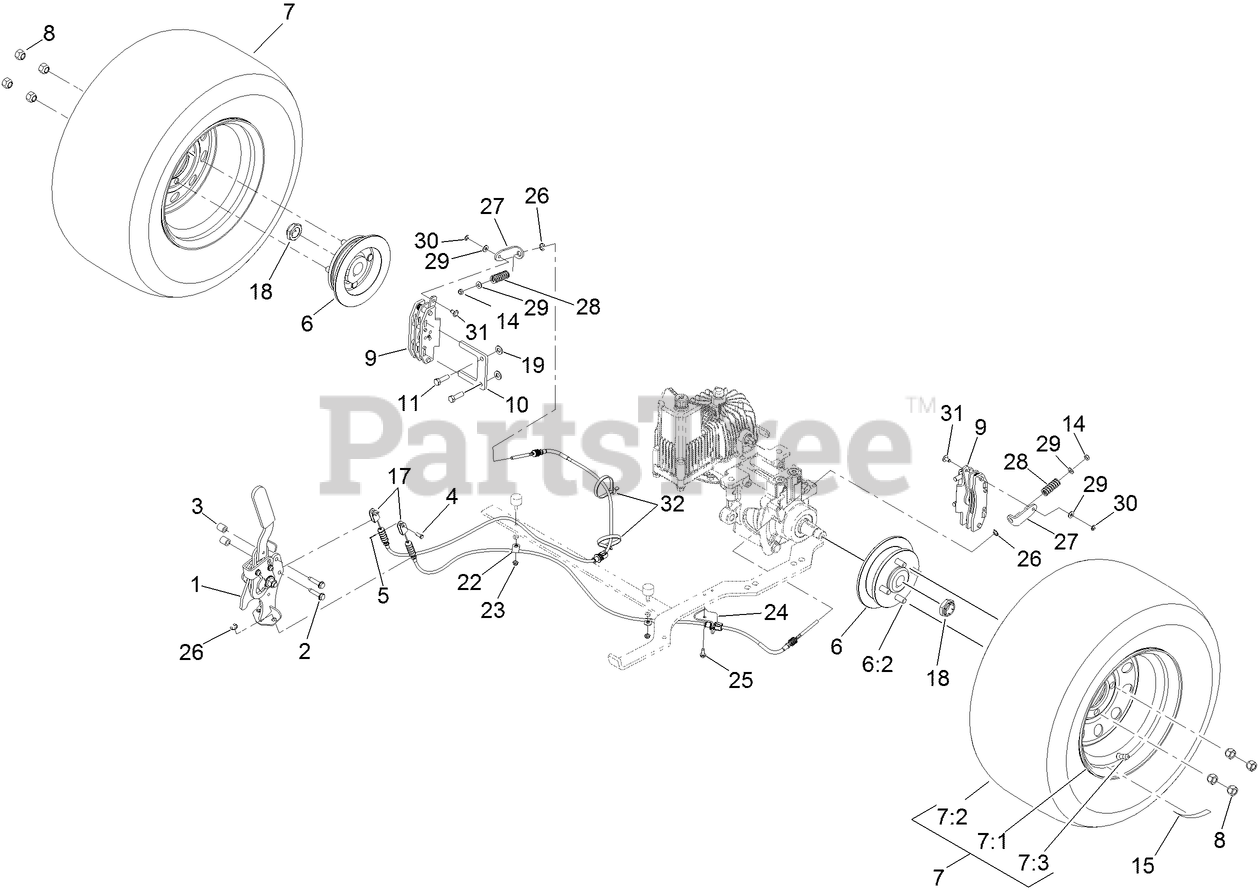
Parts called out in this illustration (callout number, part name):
1	BRAKE HANDLE ASM
3	SPACER
4	PIN-CLEVIS
5	PIN-COTTER
6	WHEEL HUB ASM
6:2	STUD-WHEEL
7	WHEEL AND TIRE ASM
7:1	RIM ASM
7:2	TIRE
7:3	STEM-VALVE
8	NUT-LUG
9	CALIPER-BRAKE
10	PLATE-MOUNT, BRAKE
11	SCREW-LOCK, PATCH
14	NUT-LOCK, NI
15	DECAL-WHEEL HUB, CE
17	CABLE-PARK BRAKE, LH
18	LOCKNUT
19	WASHER-FLAT
23	NUT-LOCK, NI
24	BRACKET-CABLE
25	SCREW-HWH
26	E-RING
27	BRACKET-BRAKE, L
28	SPRING-DIE
29	WASHER-FLAT
30	E-RING
31	PIN-BRAKE
32	TIE-CABLE
